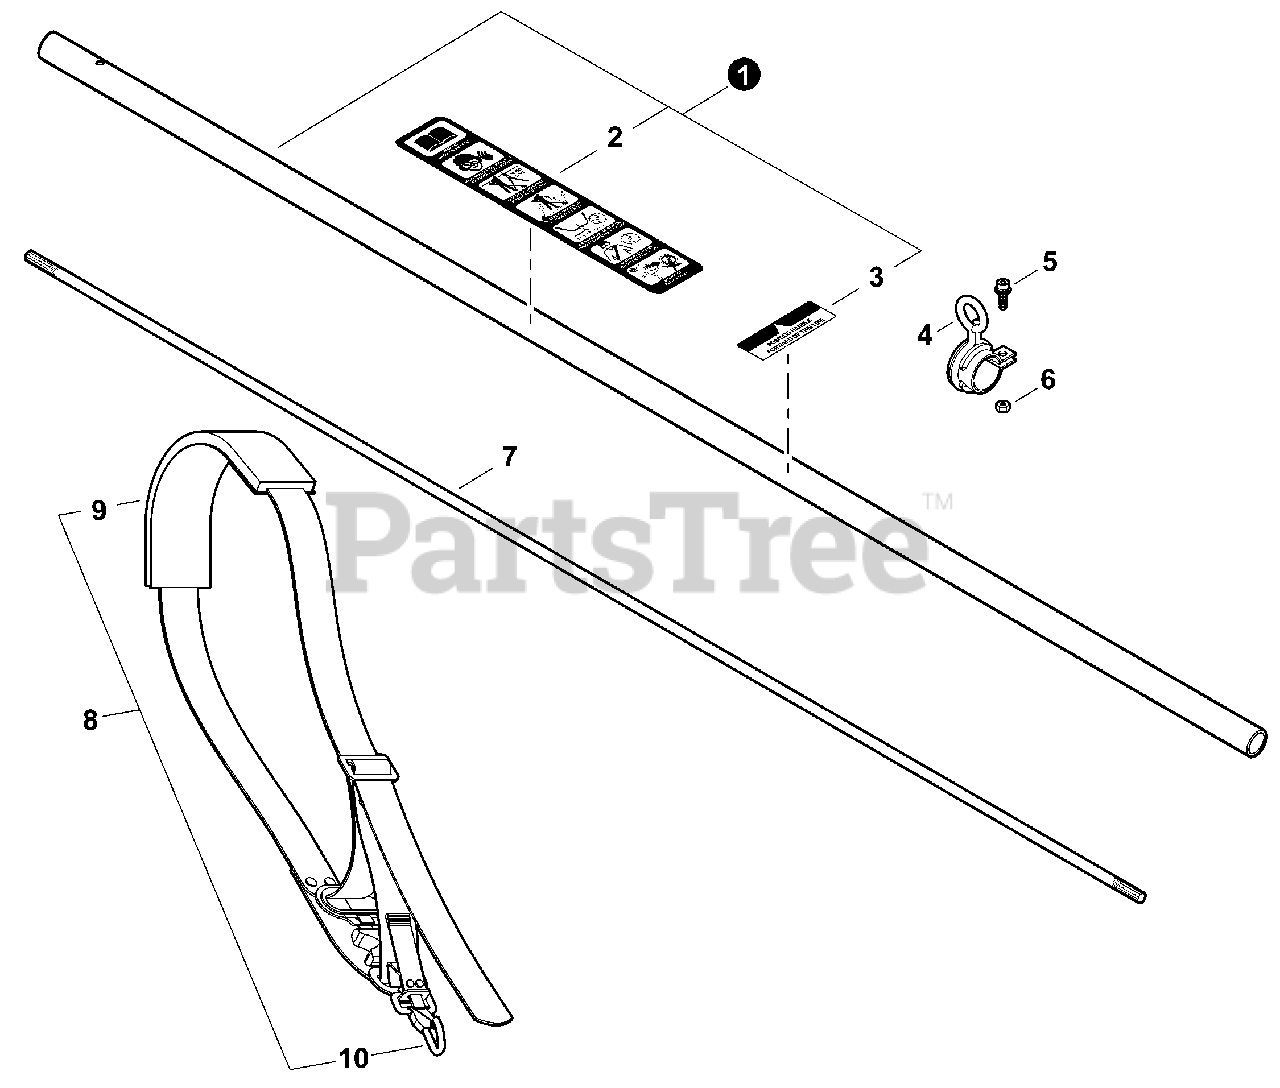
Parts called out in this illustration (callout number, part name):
1	MAIN PIPE ASSY
2	LABEL, CAUTION (BLADE CAPABLE)
3	LABEL, HANDLE
4	HANGER, SWIVEL
5	BOLT M5×12
6	NUT - 5
7	MAINSHAFT
8	HARNESS ASSY, SHOULDER
9	PAD, SHOULDER
10	HOOK, SNAP
